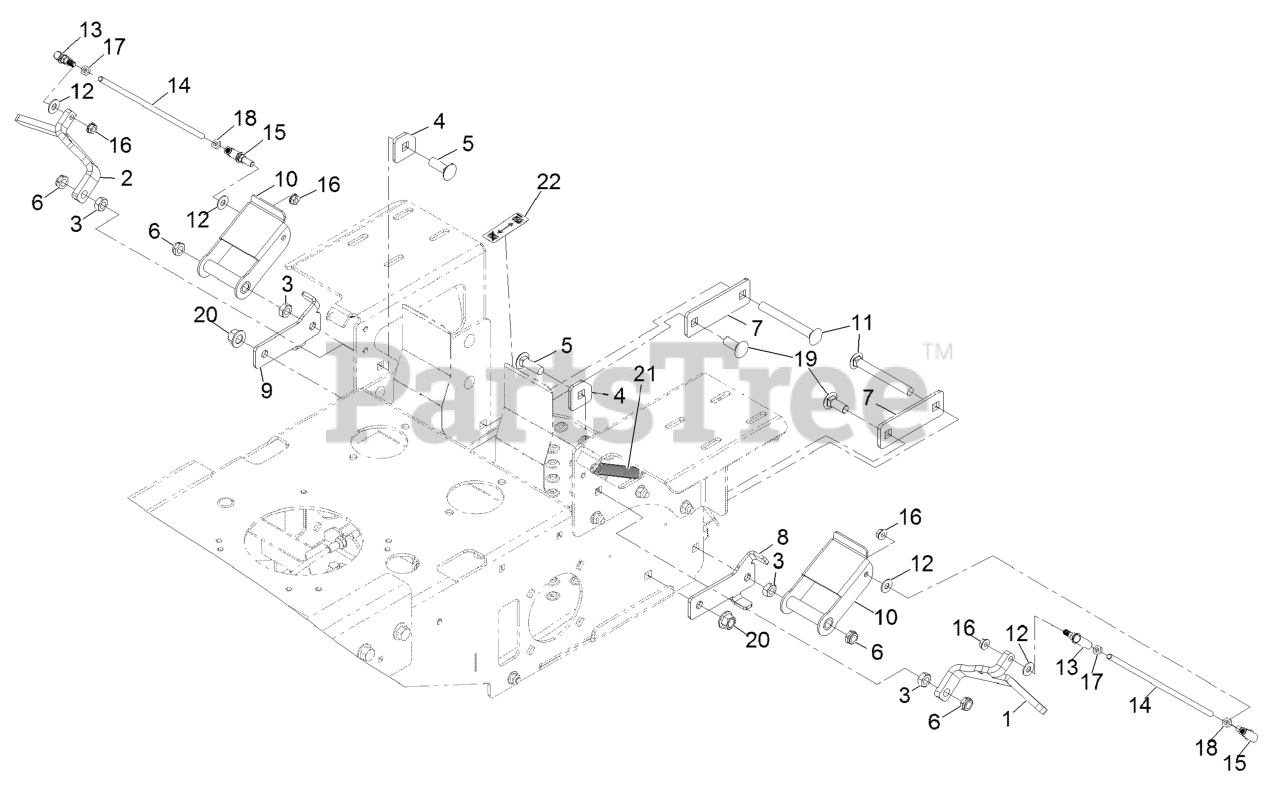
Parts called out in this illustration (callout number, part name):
1	CHOCK, L, BRAKE, JR36
2	CHOCK, L, BRAKE, JR36, MS, 0.375
3	NUT-JAM
4	BACKPLATE, BRAKE MOUNT, JR36
5	Screw-CARR
6	NUT-HEX
7	BACKPLATE, BRAKE PEDAL, JR36
8	STOP, FOOT PEDAL, BRAKE, JR36
9	STOP, JR36 FOOT PEDAL BRA
10	WLD, FOOT PEDAL, BRAKE, J
11	Screw-CARR
12	FLAT WASHER, 5/16 NOM,ST
13	3/8-24 SS BALL JOINT\N367
14	LINKAGE-BRAKE, PARK
15	Balljoint-SS
16	Nut-HHF
17	Nut-Hex
18	Nut-Hex
19	Screw-CARR
20	NUT-HEX FLANGE
21	SPRING-EXTENSION
22	DECAL-BRAKE, PARKING
